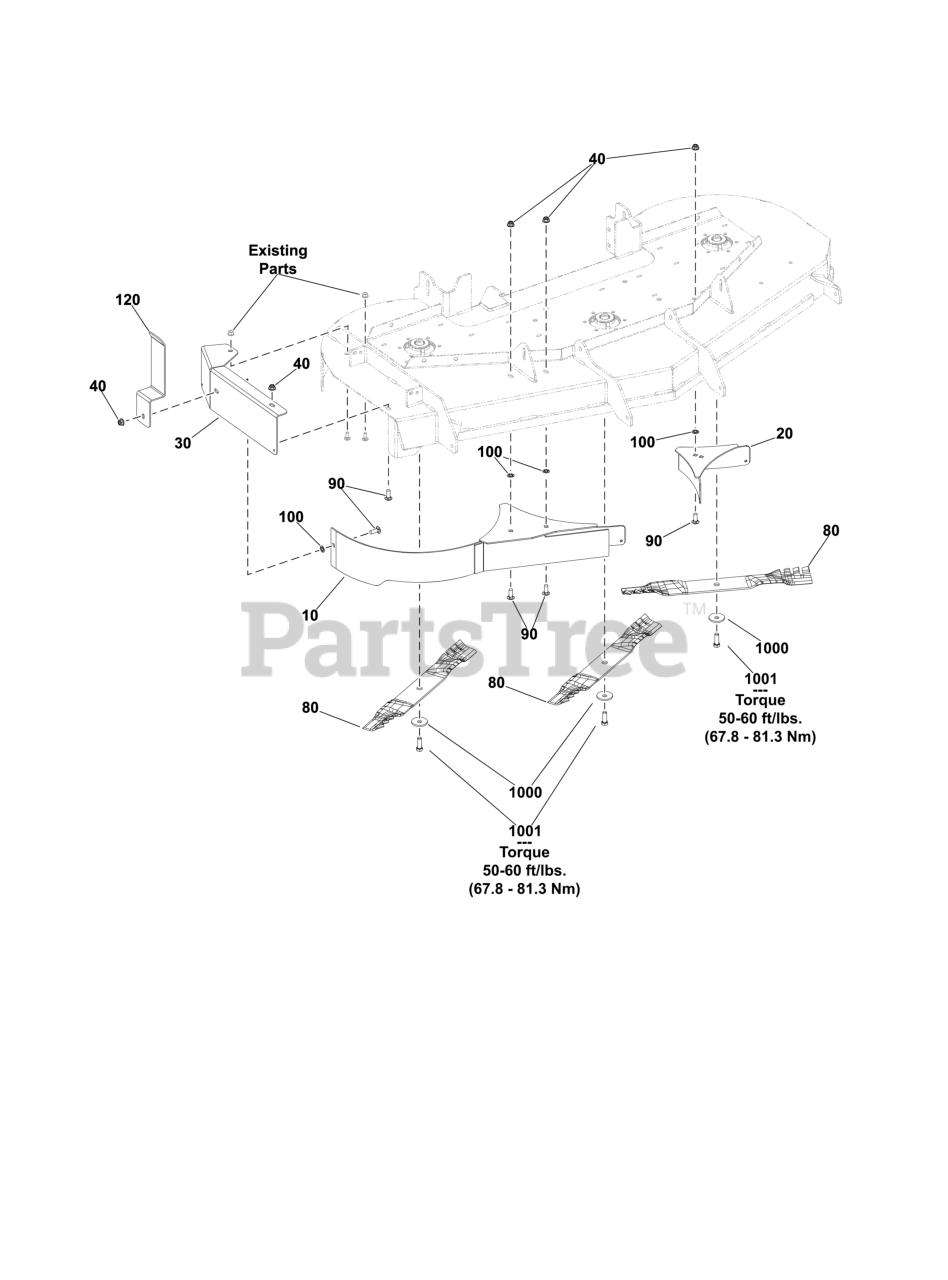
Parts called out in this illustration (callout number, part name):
10	WELD, RH BAFFLE
20	WELD, LH BAFFLE
30	PLATE, Block Off
40	NUT, Hex Flange, 3/8-16
80	BLADE, MULCHING
90	BOLT, RD SQ 3/8-16X1
100	RETAINER, PUSHNUT,3/8
120	PROP, Deflector
